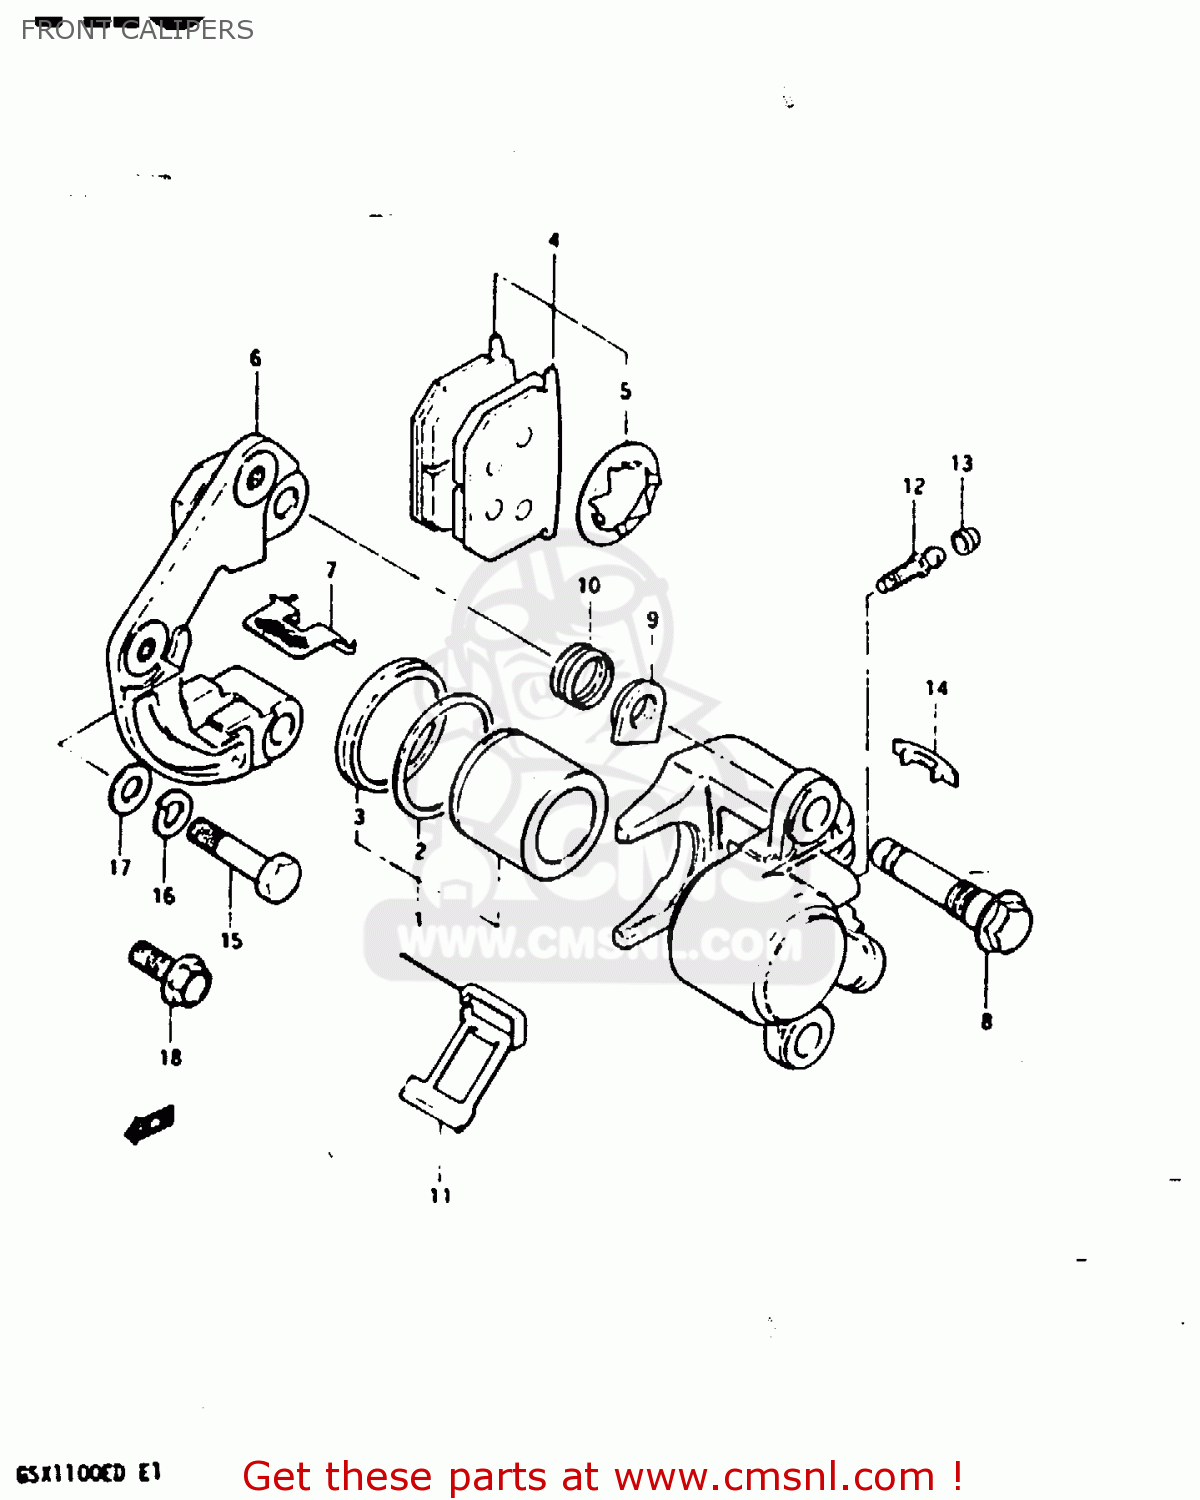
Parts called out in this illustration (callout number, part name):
1	PISTON SET
2	SEAL,PISTON
3	BOOT,PISTON
4	PAD & SHIM SET (MCA)
5	SHIM,PAD
6	HOLDER,CALIPER,LEFT
7	PAD,GUIDE
8	AXLE,CALIPER
9	NUT,CALIPER AXLE
10	BOOT
11	SPRING
12	BREATHER
13	CAP,BLEEDER PL
14	COVER,INDICATOR
15	BOLT
16	LOCK WASHER
17	WASHER
18	BOLT 10X37
